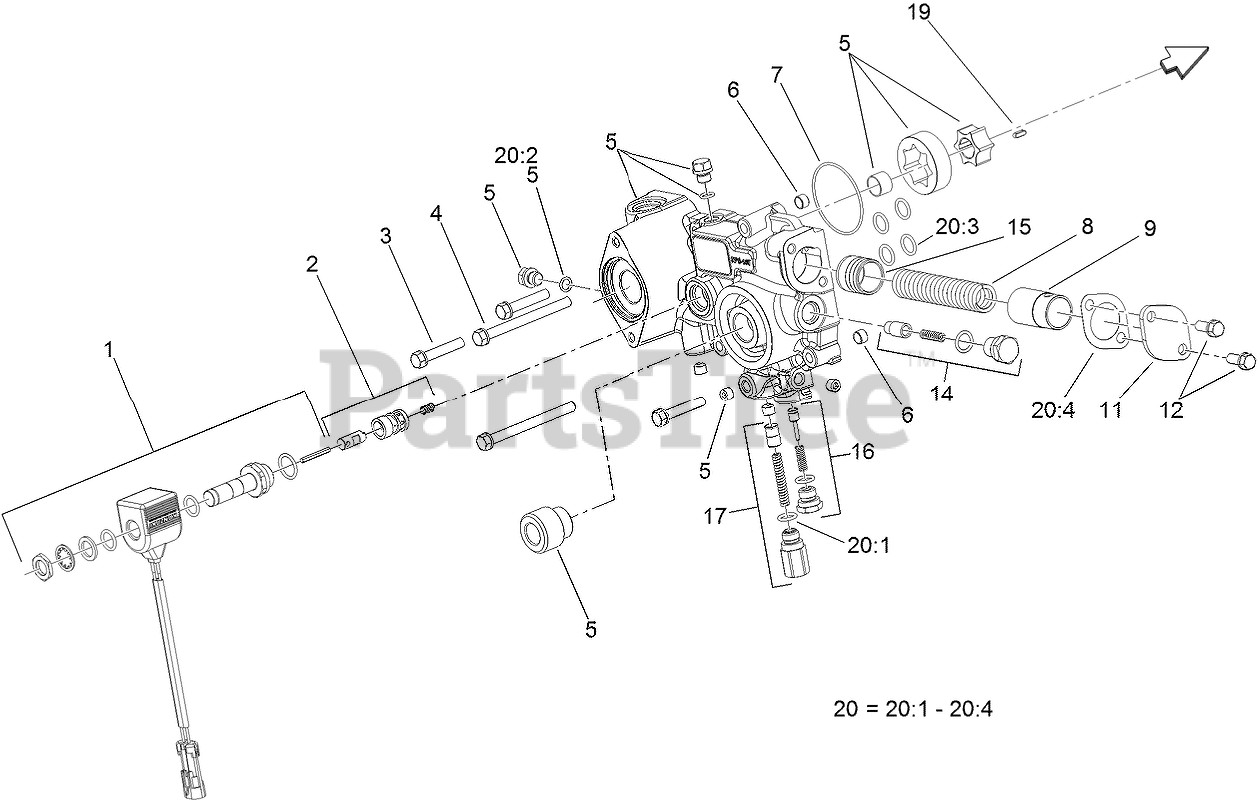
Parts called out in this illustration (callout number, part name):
1	SOLENOID ASM
2	SOLENOID VALVE ASM
5	PUMP BODY ASM
12	BOLT AND WASHER ASM
14	FILTER BYPASS VALVE ASM
16	CHARGE RELIEF VALVE ASM
17	PRESSURE VALVE ASM
20	CHARGE PUMP SEAL KIT
20:2	O RING-PLUG
20:3	Packing
